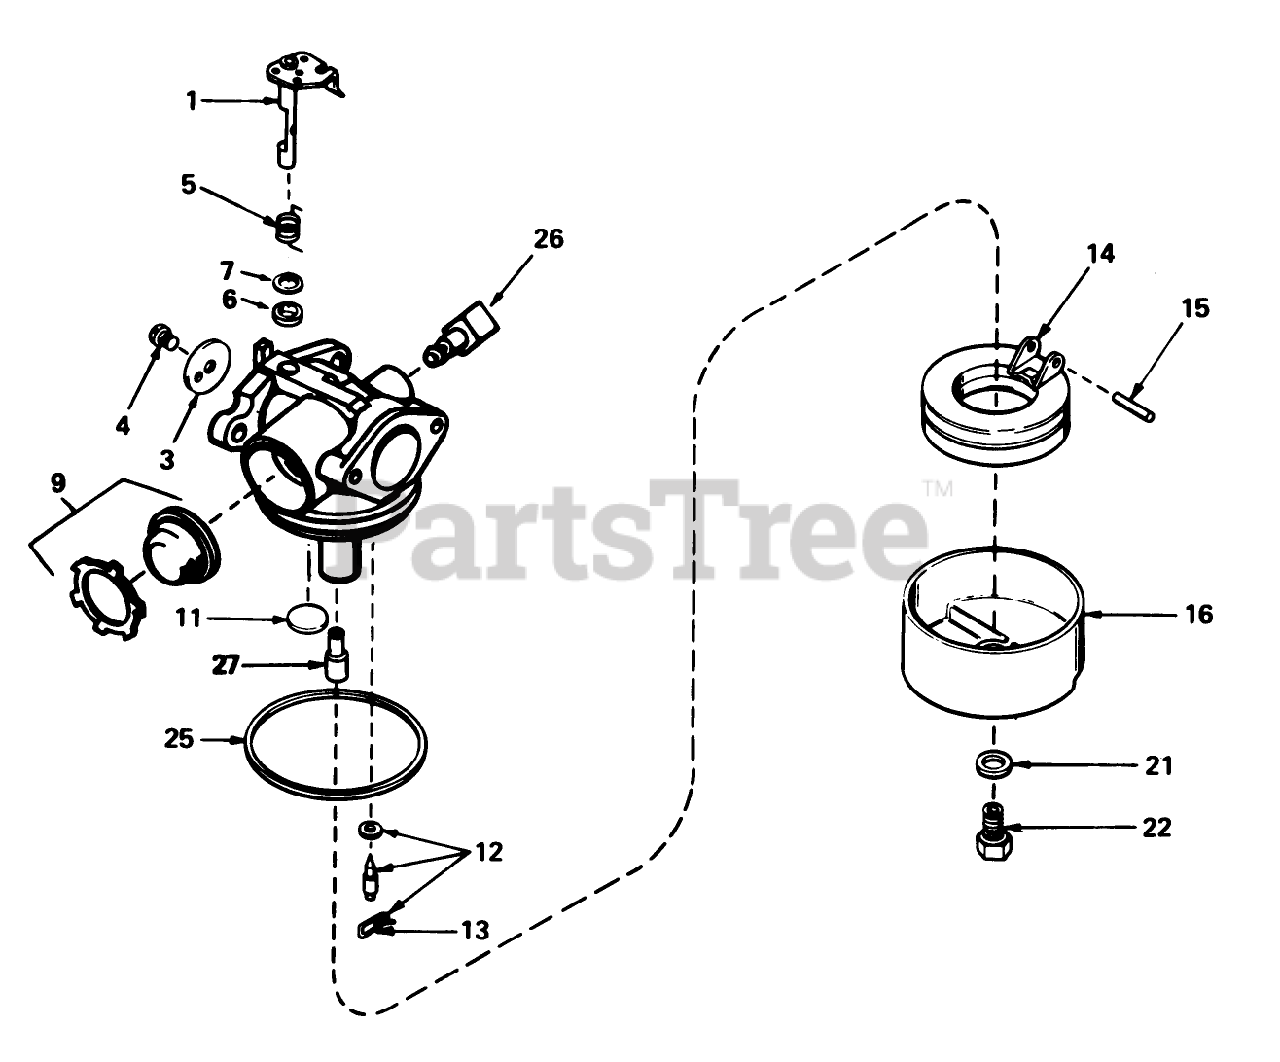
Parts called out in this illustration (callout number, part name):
1	Throttle Shaft and Lever ASM
3	Throttle-Shutter
4	Screw-Shutter
5	Spring-Return, Throttle
6	Seal-Dust
7	Washer-Seal, Dust
9	Primer Assy.
11	Plug-Welch, Atmospheric Vent
12	Inlet Needle, Seat Clip Assy. (Incl. No. 13)
13	Clip-Spring
14	Float
15	Shaft-Float
16	Bowl Float
21	Gasket-Bowl
22	Nut-Float Bowl
25	O Ring-Bowl, Float
26	Fitting-Fuel
27	Spacer
